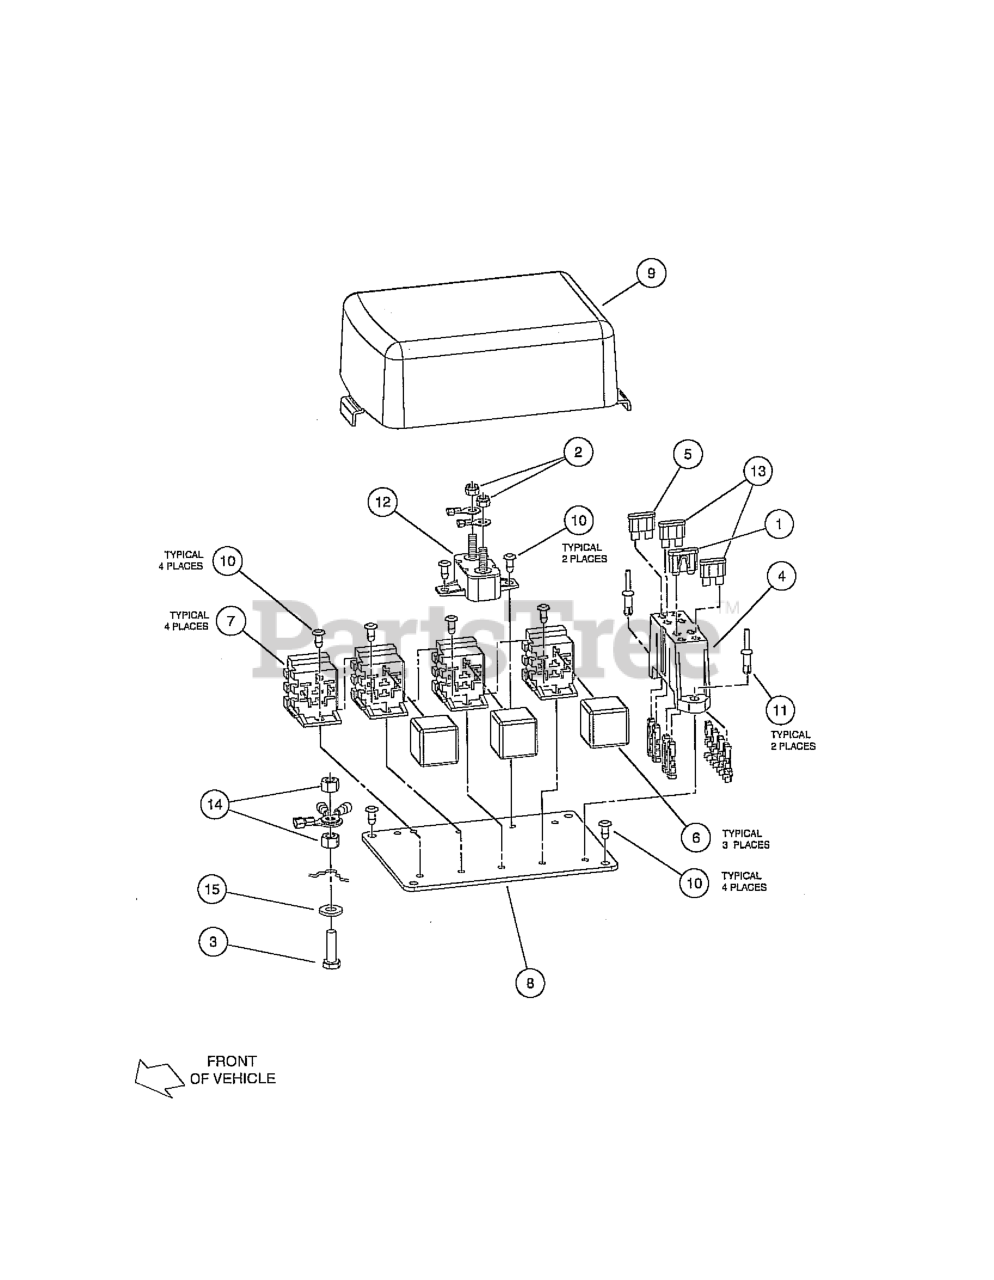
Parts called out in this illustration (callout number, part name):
1	10 AMP FUSE
4	FUSE BLOCK
5	FUSE - 20 AMP
6	RELAY, MINI ISO, SPDT
8	PLATE, ELECTRICAL
9	COVER, ELECTRICAL
10	FASTENER, PUSH-IN
11	RIVET, DRIVE
12	BREAKER, CIRCUIT, 50A
13	FUSE, ATC/ATO, 30A
14	LOCKNUT, 1/4-20 DIMPLED
15	WASHER 1/4 FLAT
